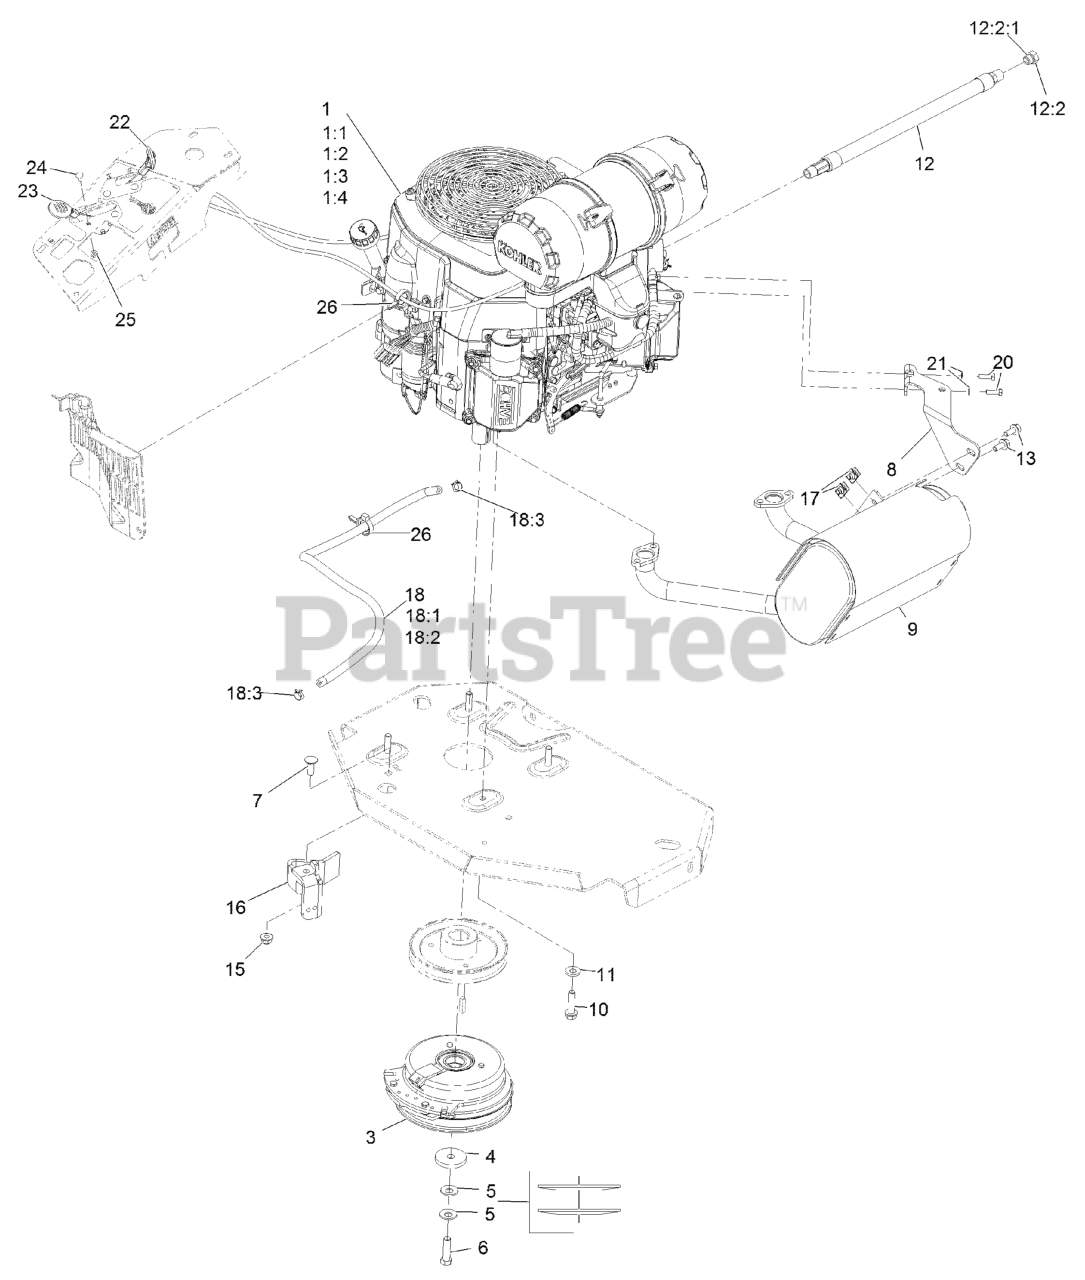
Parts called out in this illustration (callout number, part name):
1:1	Kohler 52 050 02-S Engine Oil Filter
1:2	Kohler 25 083 01-S Engine Air Filter
1:3	Kohler 25 083 04-S Safety Filter
1:4	Kohler 24 050 13-S Fuel Filter
3	CLUTCH KIT
4	WASHER-CLUTCH
5	WASHER-SPRING
6	SCREW-HH 7/16-20 X 1 1/2 W/LOCTITE
7	SCREW-CARR
8	MUFFLER BRACKET KIT
9	MUFFLER KIT
10	SCREW-HWH
11	WASHER-BELLEVILLE
12	OIL DRAIN HOSE ASM
12:2	PLUG-HH
12:2:1	O-RING
13	SCREW-HHF
15	NUT-HF, NI
16	CLUTCH-ANCHOR
18	FUEL LINE ASM
18:1	HOSE-FUEL
18:2	SLEEVE-THERMAL
18:3	CLAMP-HOSE
20	SCREW-HH M6-1 X 20Mm W/Patch
21	WASHER-SPRING
22	SHIELD-HEAT, CARBURETOR
